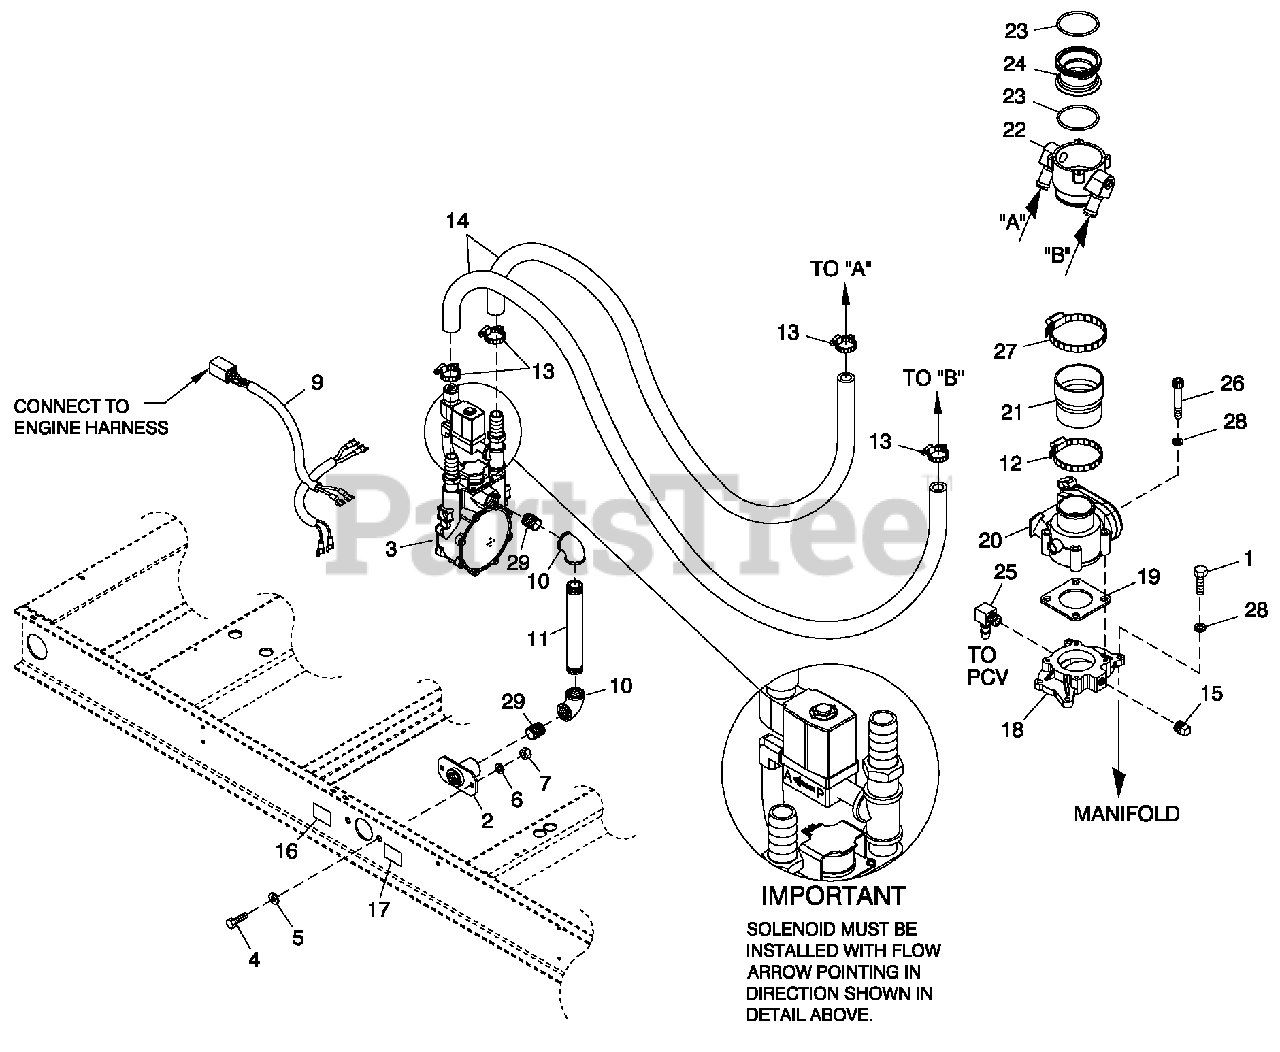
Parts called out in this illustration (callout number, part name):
1	SCREW HHC M6-1.0X 25 G8.8
2	FLANGE FUEL INLET
3	REG ASSY 5.4L 55KW L PV CPL
4	SCREW HHC M8-1.25X 20 G8.8
5	WASHER FLAT 5/16-M8 ZINC
6	WASHER LOCK M8-5/16
7	NUT HEX M8-1.25 G8 CLEAR ZINC
9	HARNESS FUEL JUMPER SINGLE REG
10	ELBOW 90D 3/4 N PT
11	NIP PLEPI PE 3/4 N PT X 7"
12	CLAM P HOSE #36 1.88-2.75
13	CLAM P HOSE #10 .56-1.06
14	HOSE 3/4 ID SAE-30R2 (38.5" LG)
15	PLUG STD PI PE 1/4 STEEL SQ HD
16	DECAL INLET PRESSURE
17	DECAL FUEL INLET NG (NATURAL GAS AP PLICATION)
18	MACHINING INTAKE ADA PTOR40MM
19	GASKET BOSCH 32 & 40
20	ACTUATOR BOSCH 40 GOVERNOR
21	REDUCER RUBBER 3.0"-2.00"
22	MIXER, 40/60MM ACTUATOR ASSY
23	O-RING 2-3/4X3/32X2-15/16
24	VENTURI THROTTLE 32MM
25	BARBED EL 90 1/4 N PTX3/8
26	SCREW SHC M6-1.0 X 50 C8.8
27	CLAM P HOSE #44 2.31-3.25
28	WASHER LOCK M6-1/4
29	NI P PLE CLOSE 3/4X1.375
